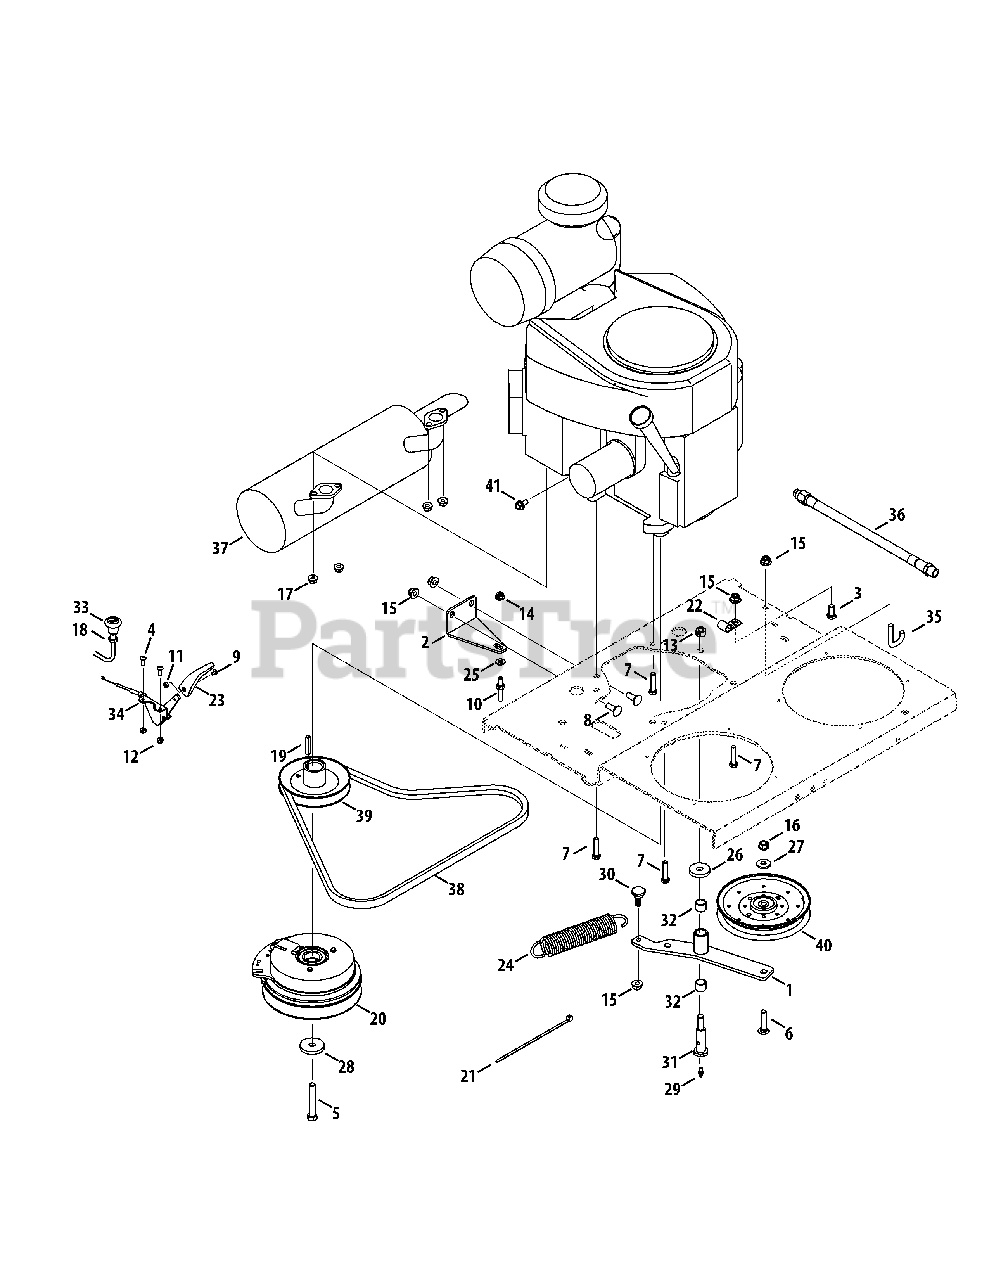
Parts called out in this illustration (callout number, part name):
1	Idler Bracket
2	Clutch Retainer Bracket
3	Hex Cap Screw, 3/8-16 x .75
4	Screw, #10-24 x .625
5	Hex Cap Screw, 7/16-20 x 2.75
6	Carriage Bolt, 3/8-16 x 1.00
7	Hex Cap Screw, 3/8-16 x 1.50
8	Carriage Bolt, 3/8-16 x 1.00
9	Screw, #8-32 x .375
10	Stud, Pivot Ball Joint
11	Nut, #8-32, Hex
12	Nut, #10-24, Hexlock
13	Nut, 7/16-14, Hexlock
14	Nut, 5/16-18, Flangelock
15	Nut, 3/8-16, Flangelock
16	Nut, 3/8-16, Flangelock
17	Nut, M8-1.25, Hexlock
18	Jam Nut, 3/8-24
19	Key, 1/4 x 1.50
20	Electric PTO Clutch
21	Cable Tie
22	Clip, .407 x 1.80
23	Throttle Control Knob
24	Extension Spring, 1.5 x 7.5
25	Washer, .344 x .688 x .065
26	Washer, .471 x 1.50 x .225
27	Washer, .406 x 1.00 x .105
28	Washer, .471 x 1.50 x .225
29	Grease Fitting
30	Shoulder Screw, .625 x .302, 3/8-16
31	Shoulder Bolt, .625 x 1.947, 7/16-14
32	bearing, .638 x .753 x .615
33	Choke Control Cable
34	Throttle Cable
35	Transmission Spring Hook
36	Oil Drain Hose
37	Muffler
39	Drive Pulley
40	Idler Pulley
41	Hex Cap Screw, M8 x 1.25 x 16MM
